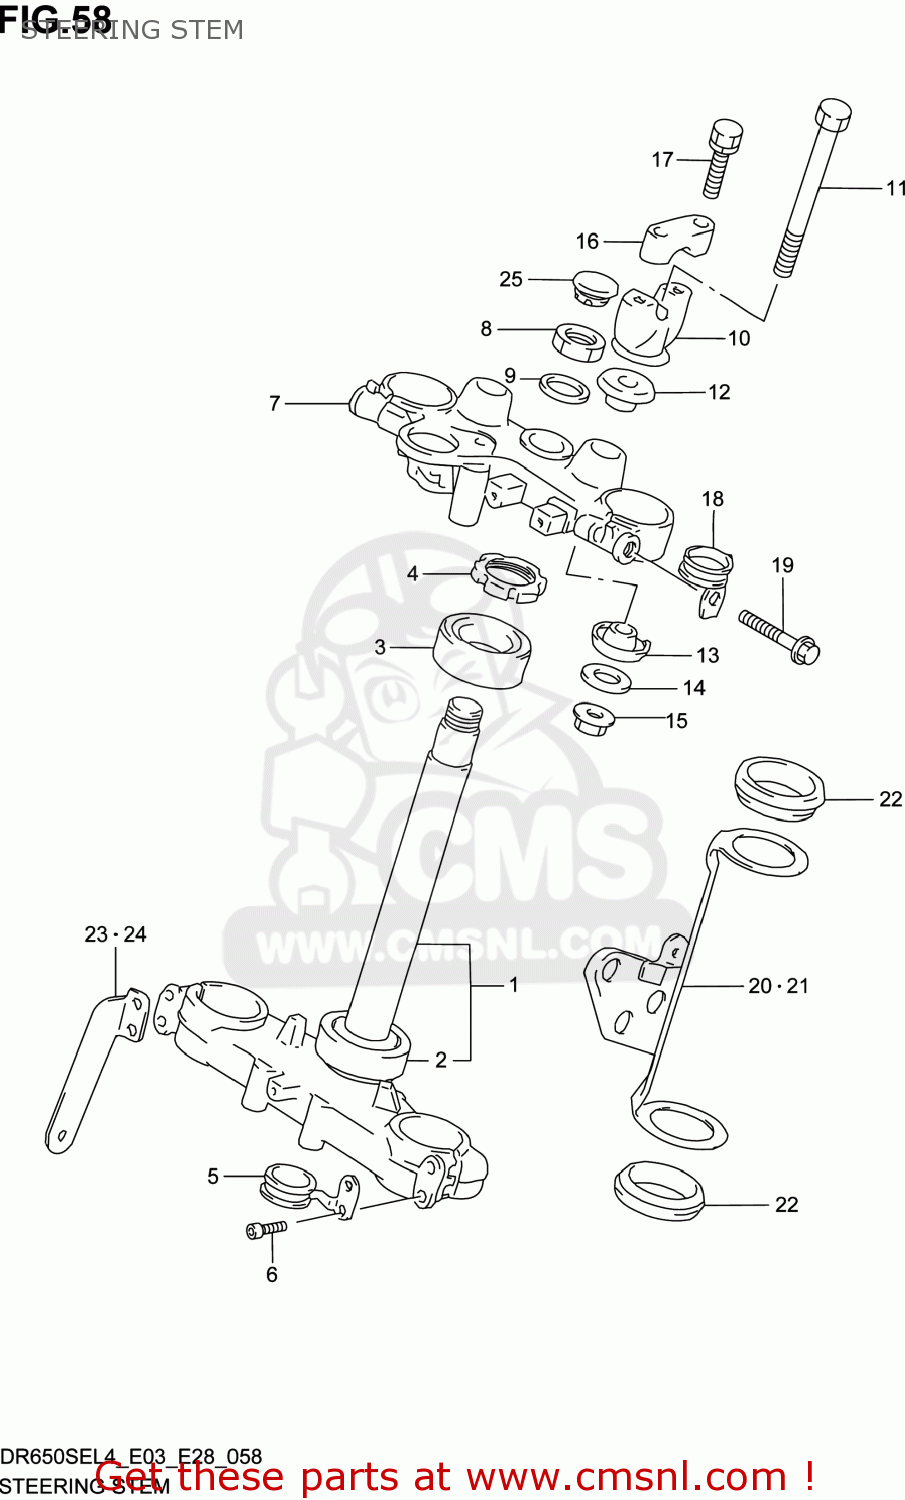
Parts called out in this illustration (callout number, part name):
1	STEM,STEERING
2	BEARING(30X52X16)
3	BEARING(30X52X16)
4	NUT,STEERING
5	GUIDE,BRAKE HOSE LWR
6	BOLT
7	HEAD,STEERING STEM
8	NUT
9	WASHER,STEM HEAD(24.5X34X1.6)
10	HOLDER,HANDLE LWR
11	BOLT
12	DAMPER,UPR
13	DAMPER,LWR
14	WASHER(10.5X28X2.3)
15	NUT
16	HOLDER,HANDLE(BLACK)
17	BOLT
18	CLIP
19	BOLT
20	COVER,FORK,R
21	COVER,FORK,L
22	DAMPER,HEADLAMP HSG BRACKET
23	BRACKET,FR SIDE REFLECTOR,R
24	BRACKET,FR SIDE REFLECTOR,L
25	CAP(OD:20)
